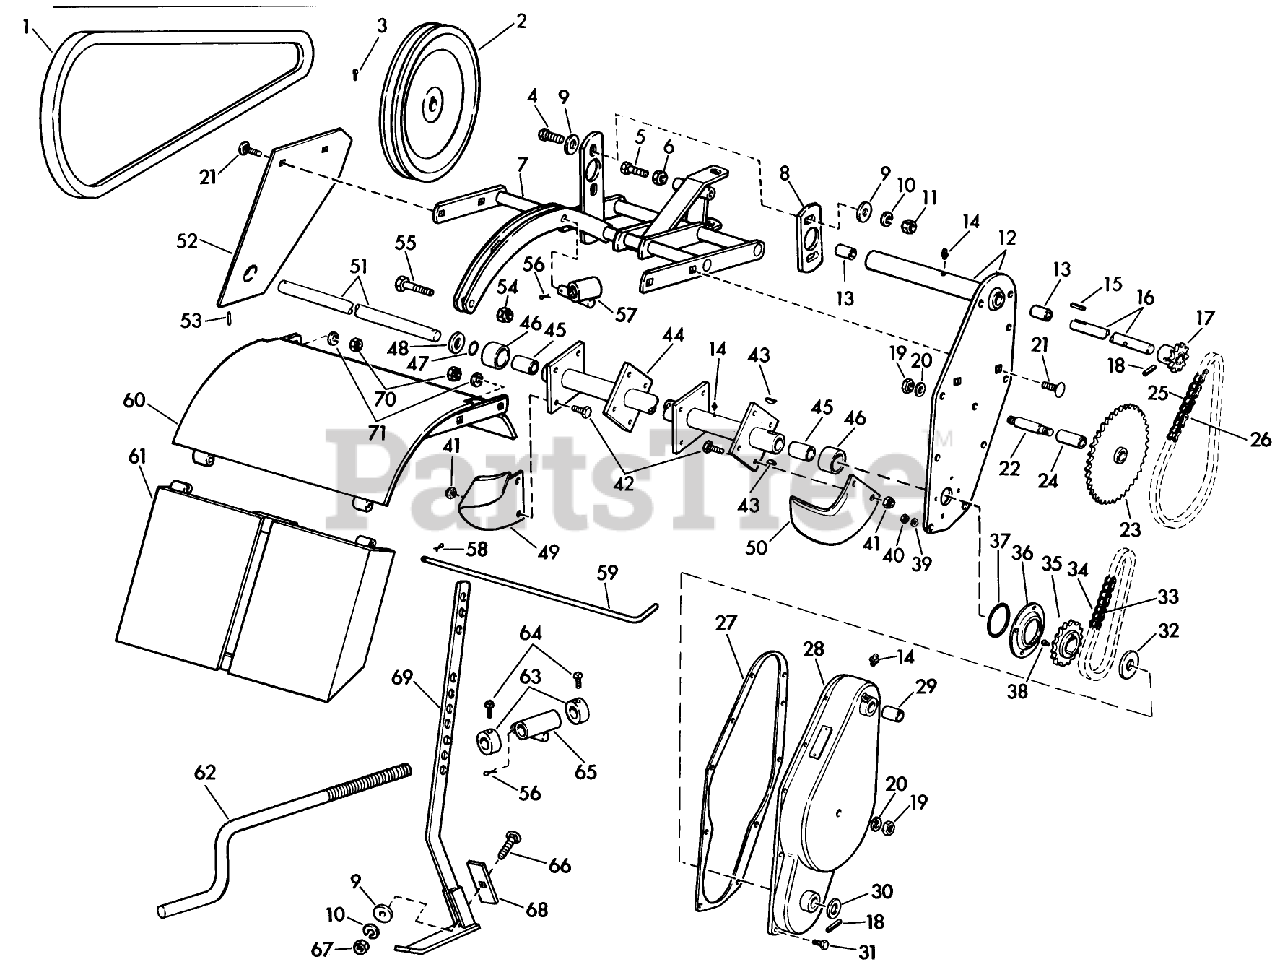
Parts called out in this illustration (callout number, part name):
1	V Belt 60" A Section
2	Pulley 10.4 OD A Section
3	Set Screw 5/16-18
4	Capscrew 5/16-18 x 7/8 Lg.
5	Capscrew 3/8-16 x 1 Lg.
6	BOOM SWITCH
7	Frame Assembly
8	Adjustable Guide
9	Washer 5/16
11	Hex Nut 5/16-18
12	Back Plate Assembly
13	Bushing
14	Grease Fitting 1/4-28 St.
16	Input Shaft
17	Input Sprocket Hub Assy.
18	Roll Pin 3/16 x 1-1/8
19	Jam Nut 1/2-20
20	Lockwasher, Shakeproof
21	Carriage Bolt 3/8-16 x 1 Lg.
22	Intermediate Shaft
23	Sprocket Cluster Assy
24	Bushing
25	Chain #41-1/2 Pitch, 55 Links
26	Connector Link
27	Side Plate Gasket
28	Cover Assembly
29	Bushing
31	Capscrew 1/4-20 x 5/8 Lg.
32	Thrust Washer
33	Chain #40-1/2 Pitch, 37 Links
34	Connector Link
35	Sprocket 18 Tooth
36	Oil Seal Retainer
37	Ring (Neoprene)
39	Lockwasher, Shakeproof
40	Hex Nut 1/4-20
41	Marsden Nut 3/8-24
42	Tine Bolt
43	Woodruff Key
44	Rotor Tube Assy.
45	Bushing
48	Thrust Washer
49	Tine LH
50	Tine RH
51	Rotor Shaft
52	Side Plate Assy.
53	Roll Pin
54	Marsden Nut 3/8-24
55	OPERATOR MANUAL
56	FUEL LINE HOSE
57	Adjusting Screw Nut
59	Hinge Rod
60	Hood Assembly
61	Hood Board Assembly
62	Adjusting Screw
64	Set Screw 5/16-18
65	AIR CLEANER TUBE ASM
66	Carriage Bolt 5/16-18 x 1-3/4 Lg.
68	Adjustable Shovel
69	Depth Shoe Assembly
70	Hex Nut 3/8-16
71	Lockwasher
